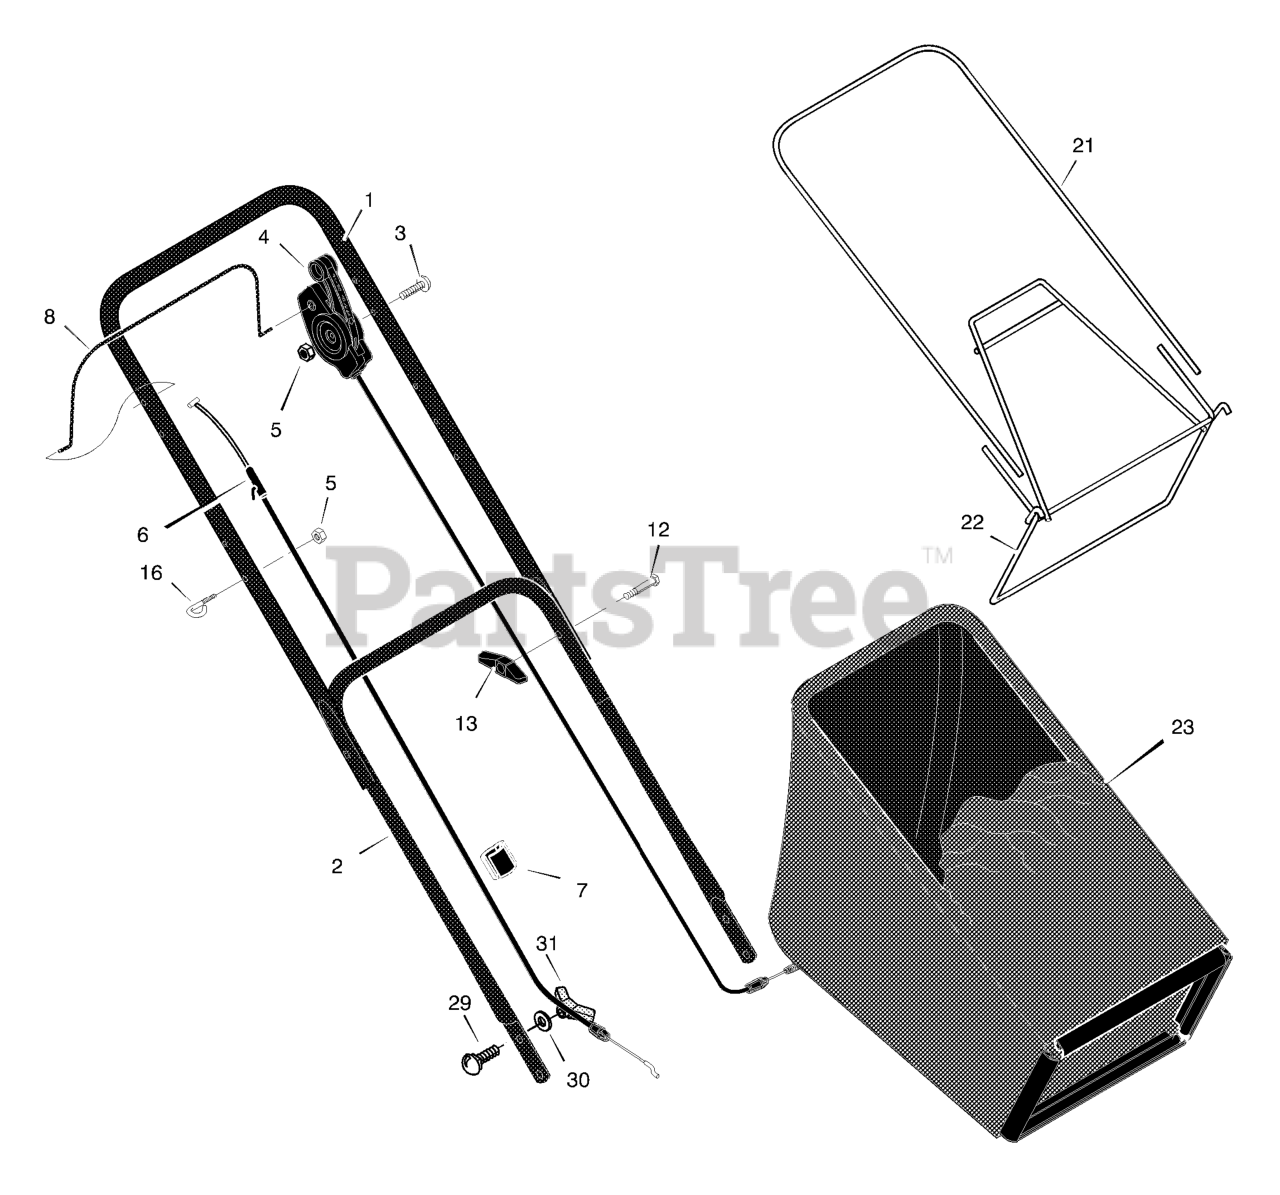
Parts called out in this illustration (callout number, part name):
1	Handle, Upper (Gray)
2	Handle, Lower (Gray)
4	Control, Drive
5	Locknut
6	Cable, Stop
7	Fastener, Single Cable
8	Lever, Stop
13	Knob
16	Guide, Rope
21	Frame, Top
22	Frame Assembly
23	Bag, Cloth
29	Bolt, Carriage
31	Knob, Plastic
